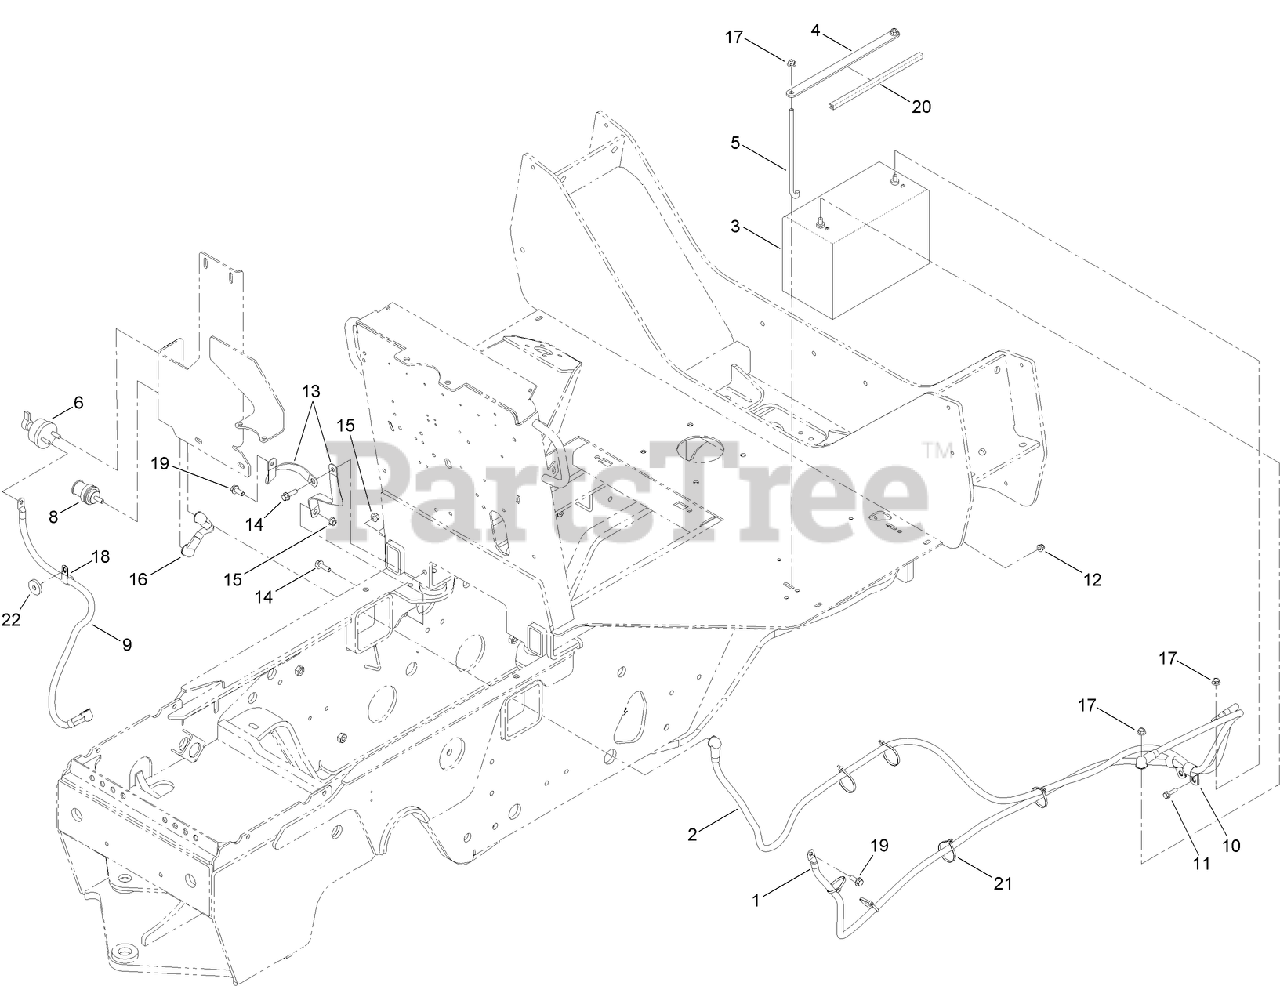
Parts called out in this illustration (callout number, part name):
1	CABLE-NEGATIVE
2	CABLE-BATTERY, POSITIVE
3	BATTERY (1000CCA, WET)
4	PLATE-HOLD DOWN, BATTERY
5	BOLT-HOLDDOWN, BATTERY
6	SWITCH-DISCONNECT, MASTER
8	POST-BATTERY, REMOTE
9	CABLE-Battery, Positive
10	CLAMP-R
11	SCREW-HHF
12	NUT-LOCK, HHF
13	STRAP-GROUNDING
14	SCREW-HHF
15	NUT-HF
16	CABLE-Positive
17	NUT-HF, NI
18	CLAMP-R
19	SCREW-HHF
20	TRIM-BATTERY
21	TIE-CABLE
22	WASHER-CLUTCH
